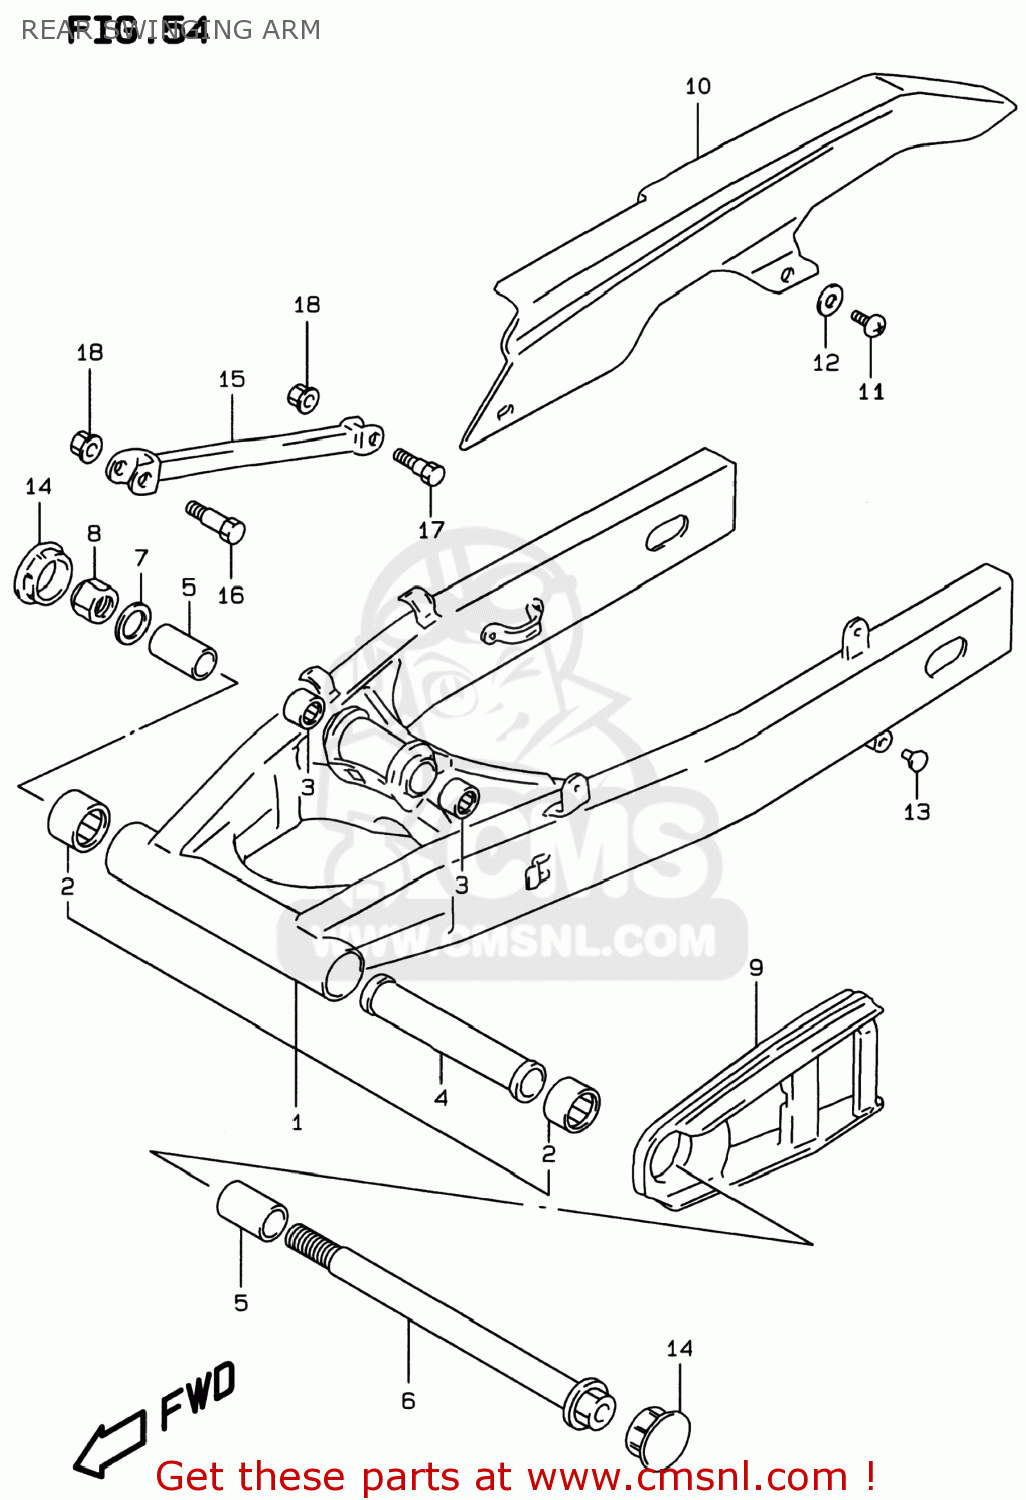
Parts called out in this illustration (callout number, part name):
1	SWINGINGARM ASSY,RR
2	BEARING(25X33X35)
3	BEARING(17X24X25)
4	SPACER(20.8X27.2X146)
5	SPACER,RR SWGARM PIVOT
6	SHAFT,RR SWINGINGARM PIVOT
7	WASHER(18.5X28X2.6)
8	NUT
9	BUFFER,CHAIN TOUCH DEFENSE
10	CASE,CHAIN
11	SCREW 6X12
12	WASHER
13	CAP(OD:12)
14	CAP,FRAME PIVOT
15	TORQUELINK,RR
16	BOLT(10X39)
17	BOLT(10X34)
18	NUT
